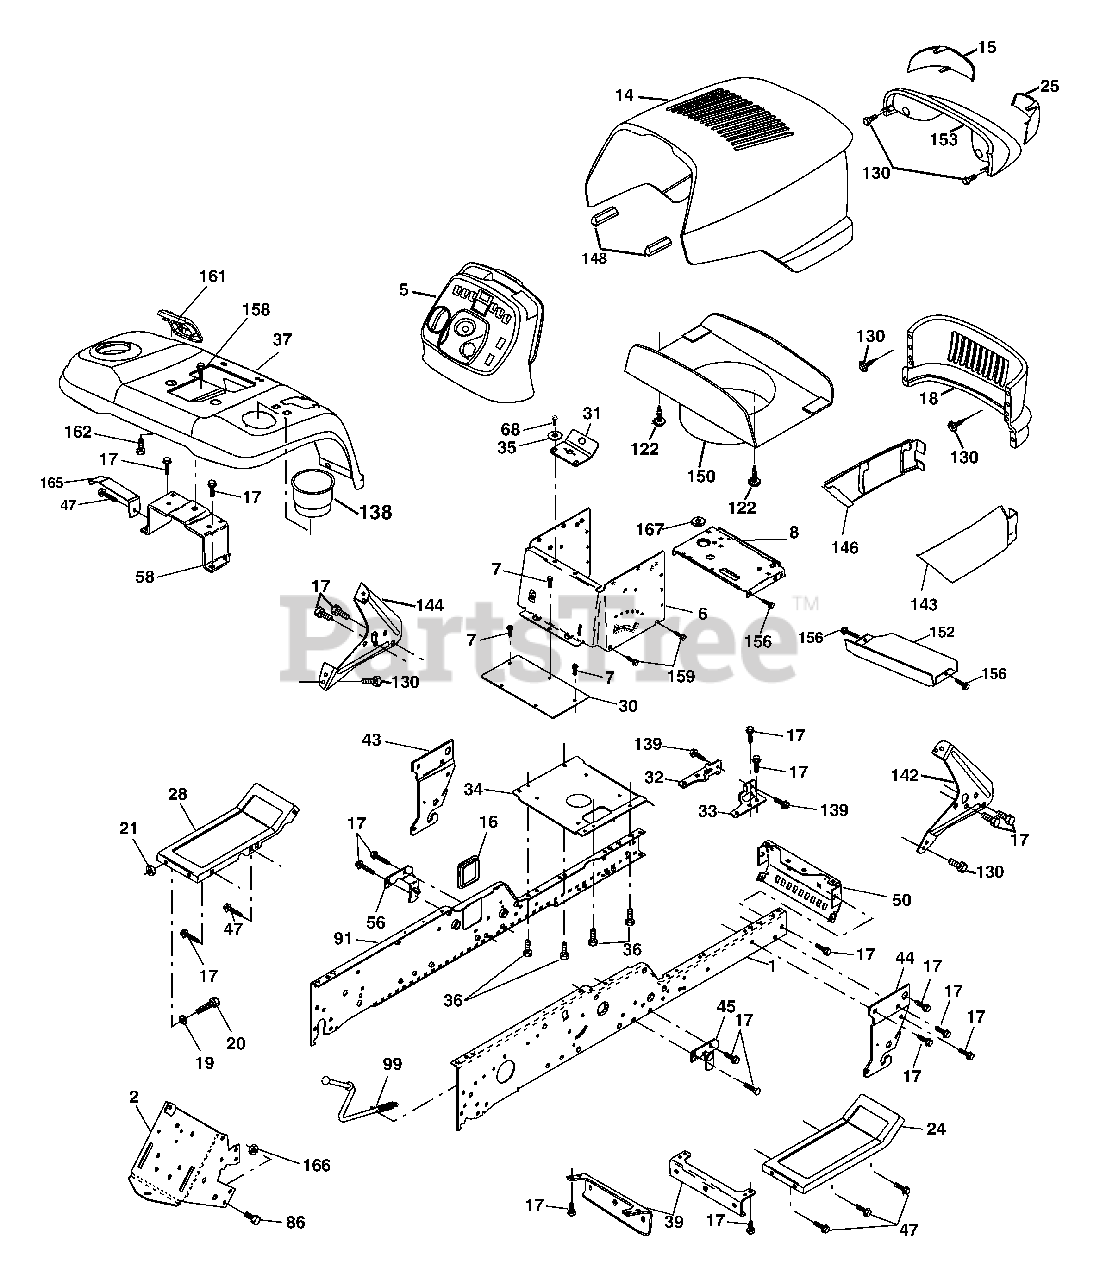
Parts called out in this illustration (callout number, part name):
1	Rail, Frame RH
2	Drawbar, Gt
5	Dash, Plastic
6	Dash, 1PCS, Lower
7	Screw, Thd Cut 1/4-20 x 1/2
8	Support, Battery
14	Hood Asm., Pnt
15	Lens LH
16	Cover, Access
17	Screw, 3/8-16 x 3/4
19	Washer 13/32 x 13/16 x 12 Ga.
20	Bolt, Fin Hex 3/8-16 x 1
21	Nut, Crownlock 3/8-16
24	Footrest, RH
25	Lens RH
28	Footrest, LH
31	Bracket Supt 1-pc Vgt Steering
32	Bracket, Frame Pivot Lh
33	Bracket, Frame Pivot Rh
34	Plate Asm Engine Chassis
35	Washer 11/32 x 11/16 x 16 Ga.
36	Screw 5/16-18 x 3/4
37	Fender, Pnt.
39	Bracket, Axle Front
43	Bracket, Spnsn Front Lh
44	Bracket, Spnsn Front Rh
45	Bracket Asm., Susp Chassis Rh
47	Screw Thdrol 3/8-16 x 1/2
50	Bracket, Chassis Front
56	Bracket Asm., Susp Chassis Lh
58	Bracket Asm., Fender
68	Screw, 5/16-18 x 1/2
86	Bolt, Fin Hex 7/16-14 unc x 1-1/4
91	Rail, Frame Lh
99	Rod Asm. Bypass
122	Screw Hex WSHD 8-18 x 7/8
130	Screw Hw Hd Hi-Lo #13-16 x 3/4
138	Cupholder
139	Bolt Shoulder 5/16-18
142	Bracket Dash Stealth RH
143	Skirt Grille RH
144	Bracket Dash Stealth LH
146	Skirt Grille LH
148	Extrusion Bumper
150	Duct Heat Hood
152	Shield, Browning
153	Light Box Asm. w/Lens
156	Screw 5/16-18 x 3/4
158	Screw 3/8-16 x 1/2
159	Screw 3/8-16 x 3/4
161	Console Fuel Window
162	Screw Hex 1/4-1/2 unc
165	Bracket Support Tank
166	Nut, Crown Lock 7/16-14 unc
167	Bushing Snap
